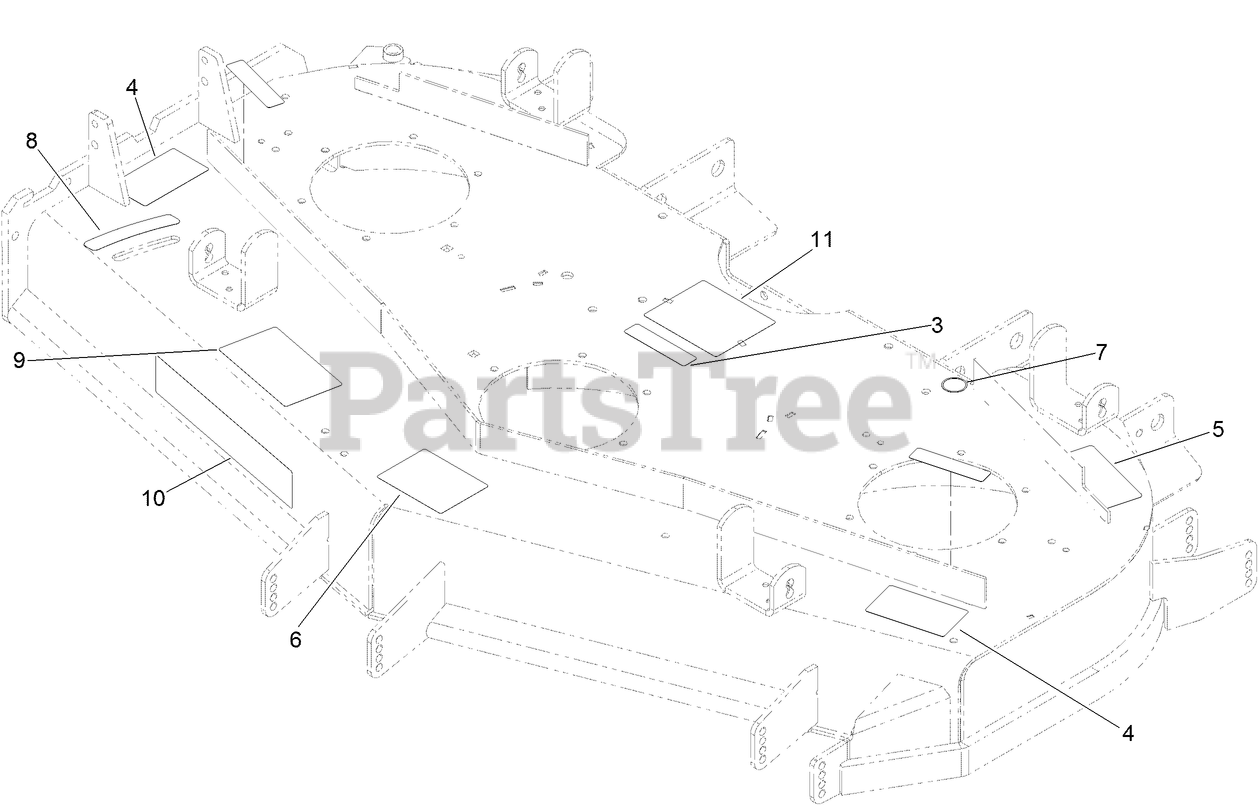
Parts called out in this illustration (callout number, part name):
3	DECAL-WARNING
4	DECAL-DANGER
5	DECAL-TORQUE, BLADE BOLT
6	DECAL-ANTI SCALP
7	DECAL-GREASE
8	DECAL-SETTING, BAFFLE
9	DECAL-ADJUSTMENT, BAFFLE
11	DECAL-ROUTING, BELT
